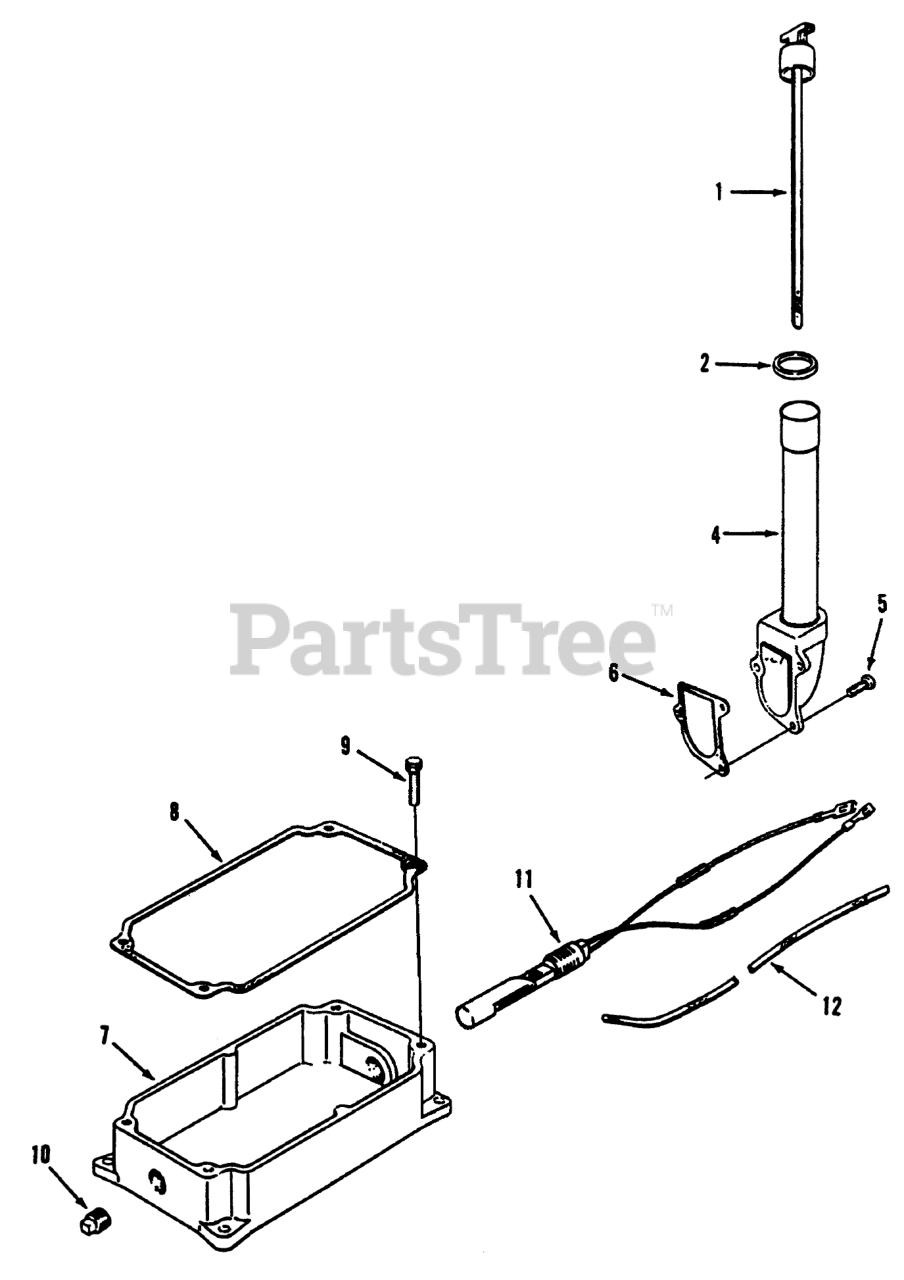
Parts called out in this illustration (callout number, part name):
1	Dipstick
2	0-Ring
4	Adapter-Oil Fill
5	Screw
6	Gasket
7	Oil Pan
8	Gasket
9	Screw
11	Kit-Float Switch (Includes Items 12 & Decal)
12	Sleeve
